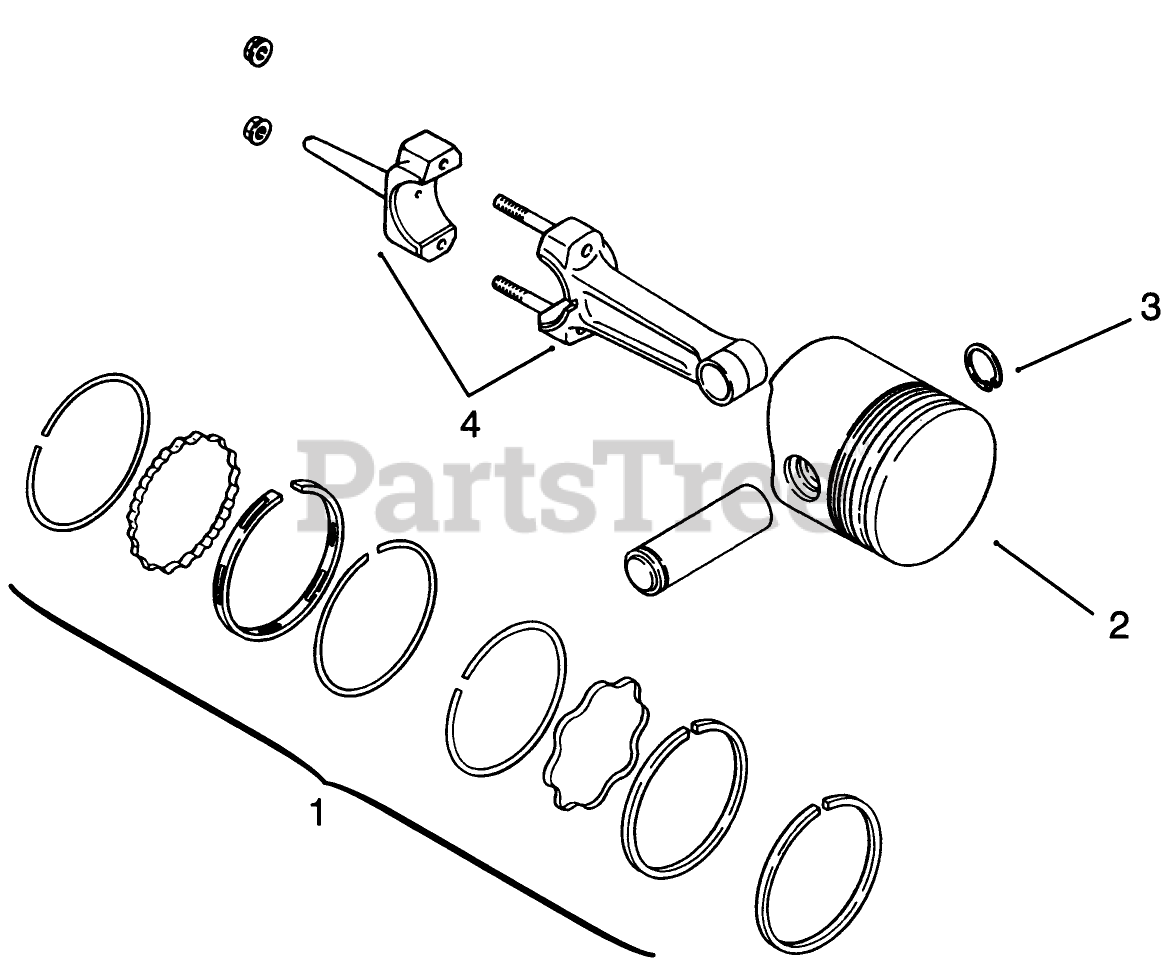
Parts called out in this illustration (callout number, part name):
1	KOHLER 47-108-01
2	KOHLER 47-874-16
3	KOHLER 47-018-01
4	KOHLER 45-067-24
